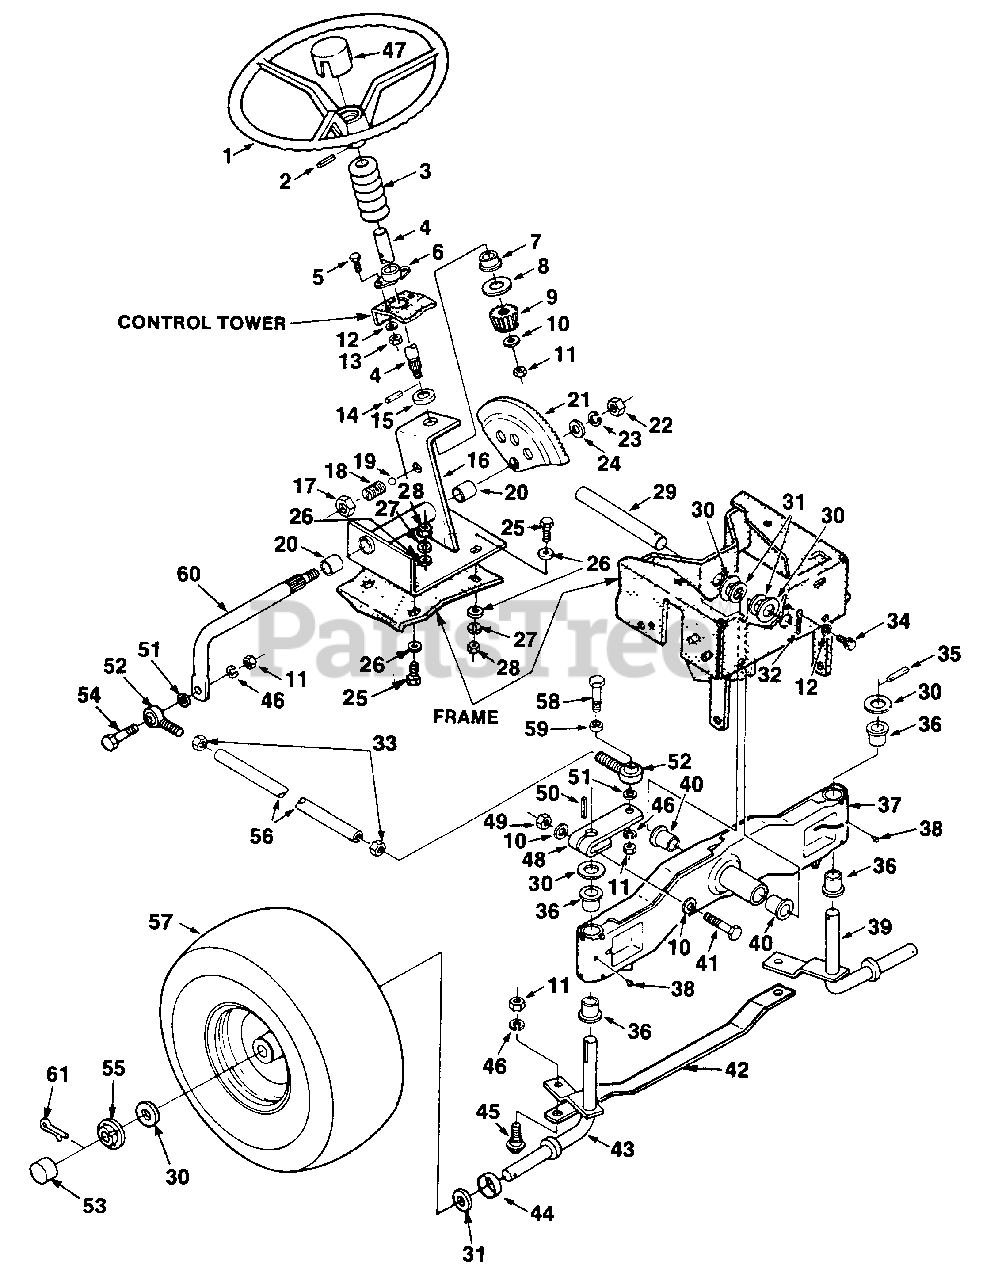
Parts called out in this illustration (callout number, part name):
1	WHEEL- Steering
2	PIN- Roll
3	BELLOW- Steering
4	SHAFT- Steering Wheel
5	SCREW- (1/4-20 x 1/2")
6	BEARING- Steering Shaft
8	WASHER- Front Hub
9	PINION- Steering
11	NUT- Hex (3/8-16)
12	WASHER- Lock (1/4-20)
13	NUT- Hex (1/4-20)
14	PIN- Roll
15	SPACER- Steering
16	SUPPORT- Steering
17	NUT- (5/8-11)
18	SPACER- Steering Gr
19	BALL-.312 Dia
21	GEAR- Steering
22	NUT- (1/2-13)
23	WASHER- Lock hvy (1/2")
24	WASHER- Flat (1/2")
25	SCREW- Hex (5/16-18 x 7/8")
26	WASHER- Flat (5/16")
27	WASHER- Lock (5/16")
28	NUT- Hex (5/16-18)
30	WASHER- Flat (3/4")
31	SPACER- Axle
32	PIN- Cotter (1/4 x 1 1/2")
33	NUT- (3/8-24)
34	SCREW- (1/4-20 x 3/4")
36	BUSHING- Spindle
37	AXLE- Front
38	FITTING- Grease
39	SPINDLE- L.H.
41	SCREW- (3/8-16 x 2 1/4")
43	SPINDLE- R.H.
45	BOLT- Tie Bar Mtg
46	WASHER- Lock (3/8")
47	CAP- Steering Wheel
48	ARM- Steering
49	NUT- Centerlock (3/8-16)
51	SPACER- Balljoint
52	JOINT- Ball
54	SCREW- (3/8-16 x 1 1/2")
55	WASHER- Wheel retaining
56	TUBE- Drag link
57	RIM & TIRE ASSY
58	SCREW- (3/8-16 x 1 3/4")
59	SPACER- Balljoint
60	PITMAN ARM
